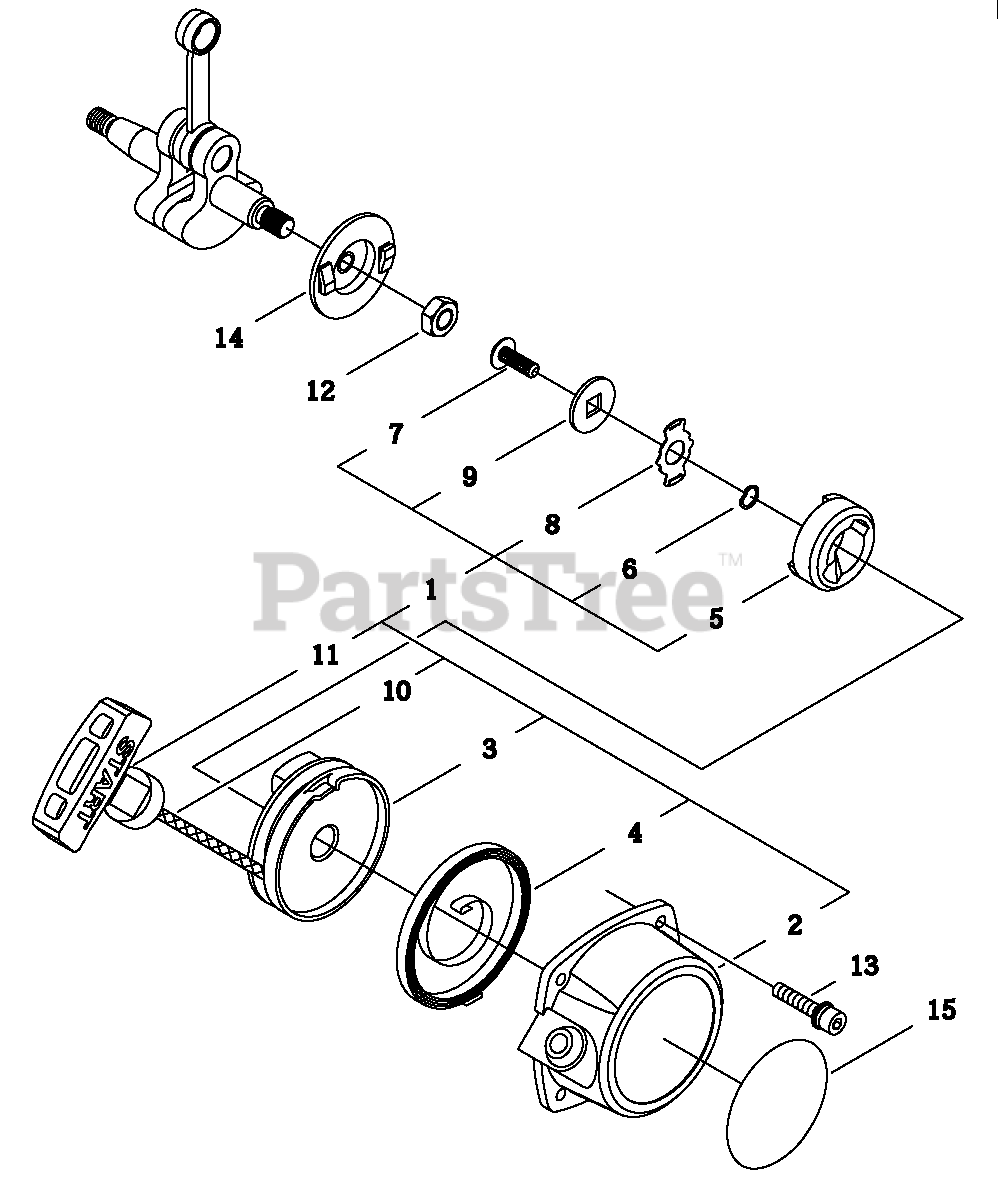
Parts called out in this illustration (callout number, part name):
1	STARTER ASSY, RECOIL
2	CASE, RECOIL STARTER
3	REEL, ROPE
4	SPRING, RECOIL
5	RATCHET
6	WASHER, WAVE
7	SCREW 5 MM
8	RETAINER
9	WASHER 5 MM
10	ROPE, STARTER
11	GRIP, STARTER
12	NUT M8×1
13	BOLT, ADHESIVE M4×12
14	PULLEY, STARTER
15	LABEL, ID
